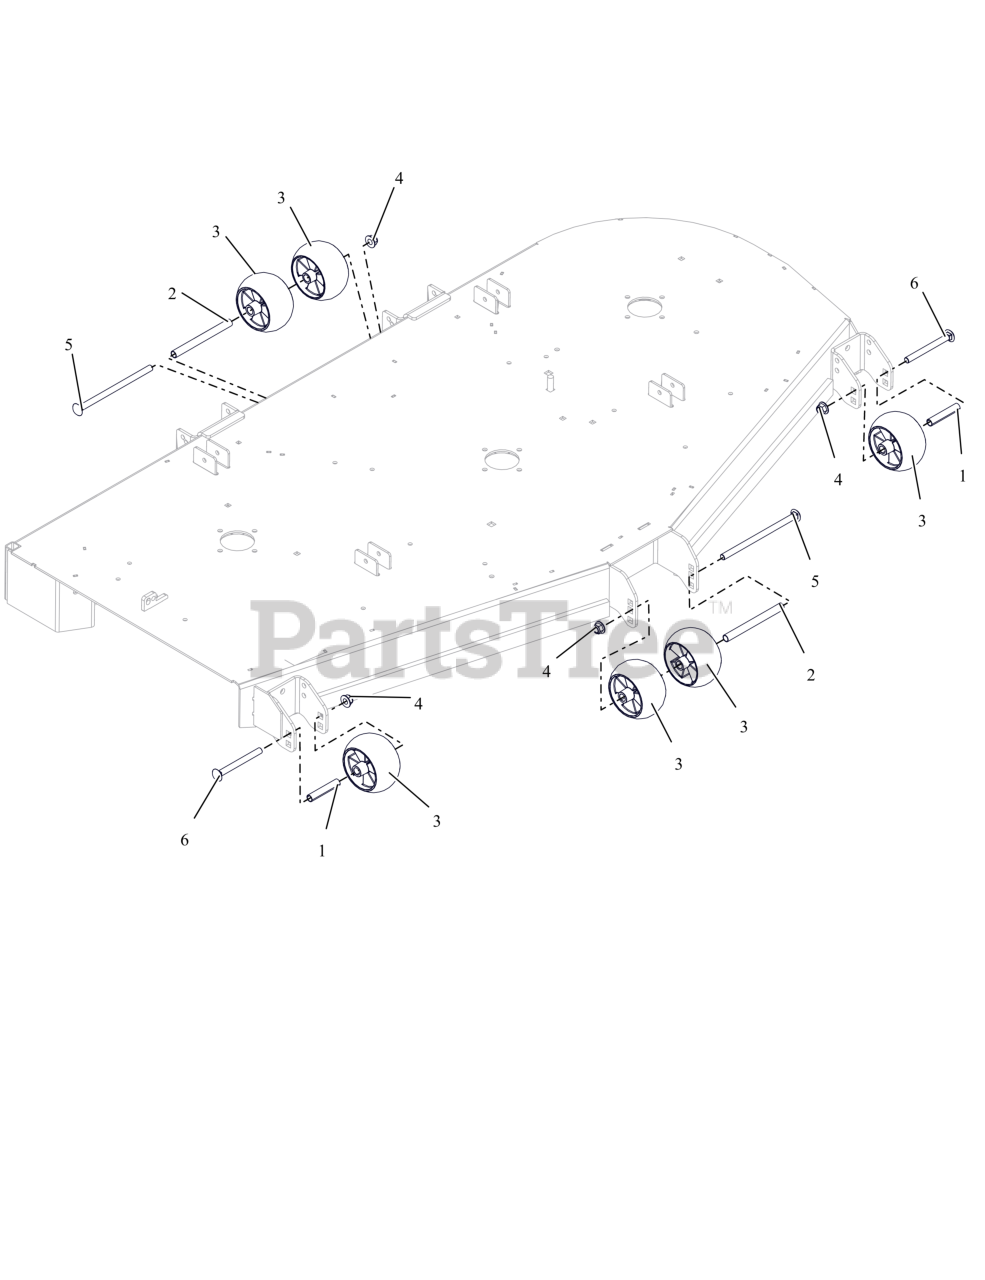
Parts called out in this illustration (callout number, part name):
1	SPACER, .510X.625X3.35
2	SPACER, .510X.625X6.50
3	ANTI-SCALP WHEEL - 5X3 CTR
4	NUT,NYL-FLG .50-13 GF ZCC
5	BLT, RHSN .50-13X8.50 G5 ZCC
6	BLT, RHSN .50-13X5.00 G5 ZCC
